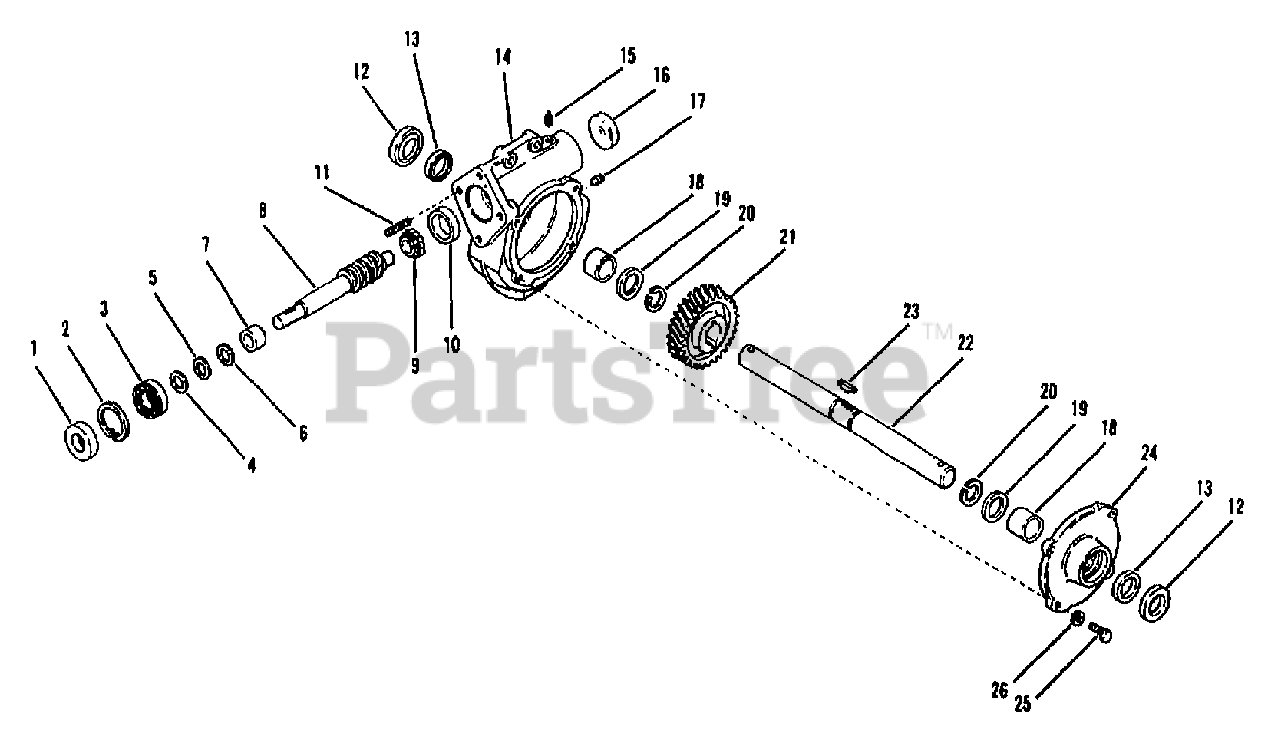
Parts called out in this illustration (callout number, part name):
1	SEAL-OIL
2	RING-RETAIN INT 2.062 DIA
3	BEARING-BALL
4	SHIM-1.25X1.01X.06
5	SHIM-1.25X1.0X.02
6	SHIM-1.359X1.013X.005
7	SPACER-1.25X.995X.714
8	SHAFT
9	CONE-BEARING
10	CUP-BEARING
12	SEAL-OIL
13	SEAL-OIL
14	CASE-GEAR
15	VALVE
17	PLUG-SQ HEAD 1/4-18 NPT
18	BEARING
19	WASHER
20	RING-RET. EXT 1.25 ID
22	SHAFT
23	KEY-HI PRO .25X1.5
24	COVER
25	SCR-HH 5/16-18X1.0 G5 ZP
26	WASHER-LK .312 ZP
